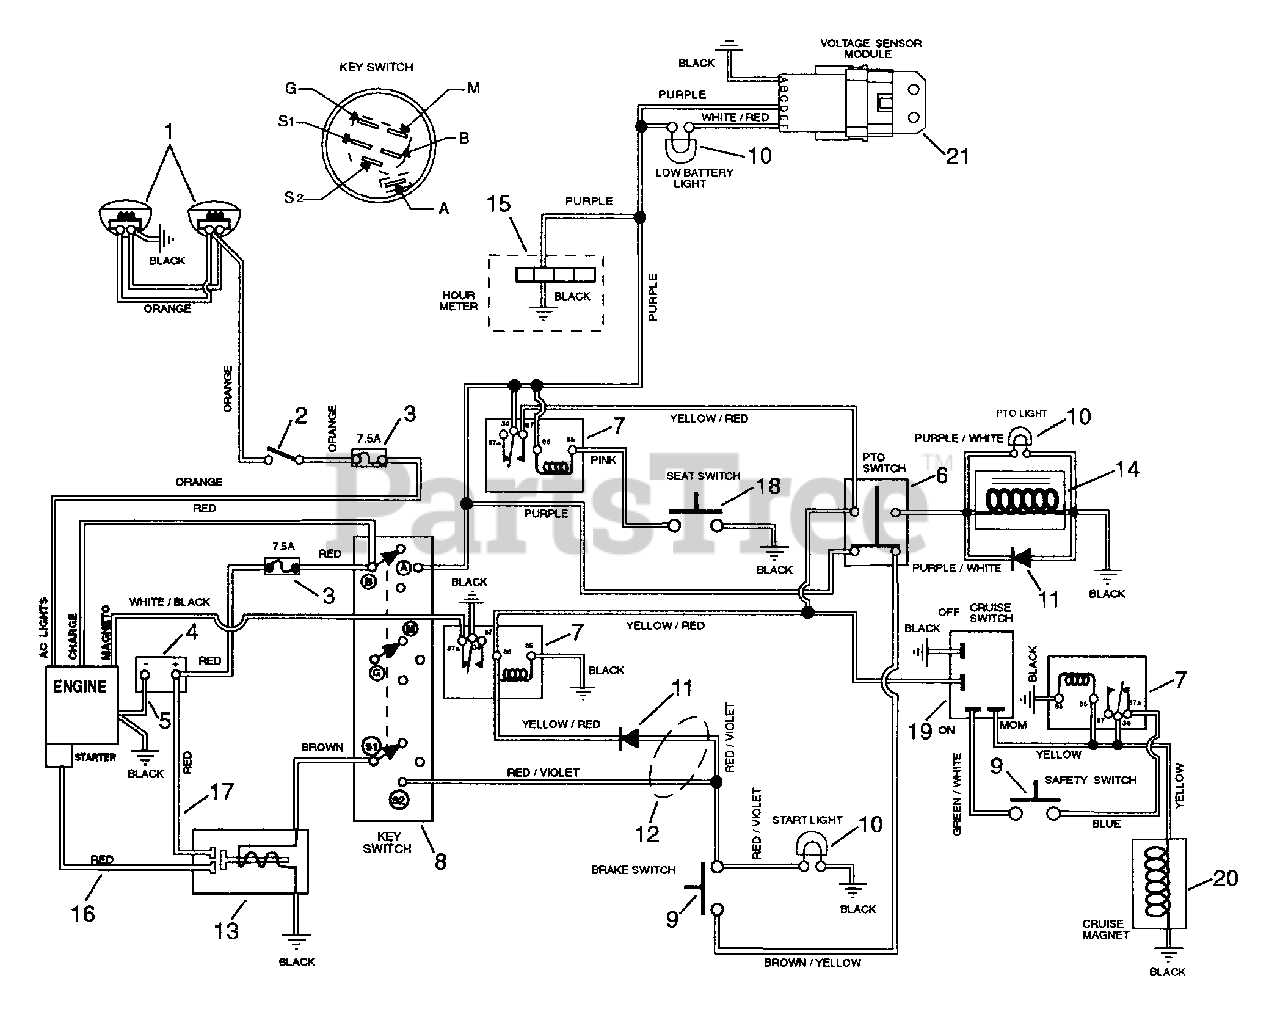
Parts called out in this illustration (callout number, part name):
1	HEADLIGHT- RH
2	SWITCH - LIGHT
3	7.5 AMP Fuse
4	BATTERY W/TUBE
5	GROUND CABLE .31X22.00X.31
6	PTO KNOB/ SWITCH ASSY
7	RELAY
8	KEY SWITCH
9	SWITCH- SINGLE POLE N.O.
10	#194 Bulb
11	MOLDED DIODE PLUG 1 AMP
12	WIRE HARNESS - 1340H TEC
13	SOLENOID
14	ELECTRIC CLUTCH/BRAKE(1.8AMP)
15	HOURMETER KIT- SIERRA
16	START CABLE 22"
17	STARTER CABLE 6.75"
18	SWITCH- SEAT
19	SWITCH - CRUISE
20	MAGNET
21	MODULE - VOLTAGE SENSOR
